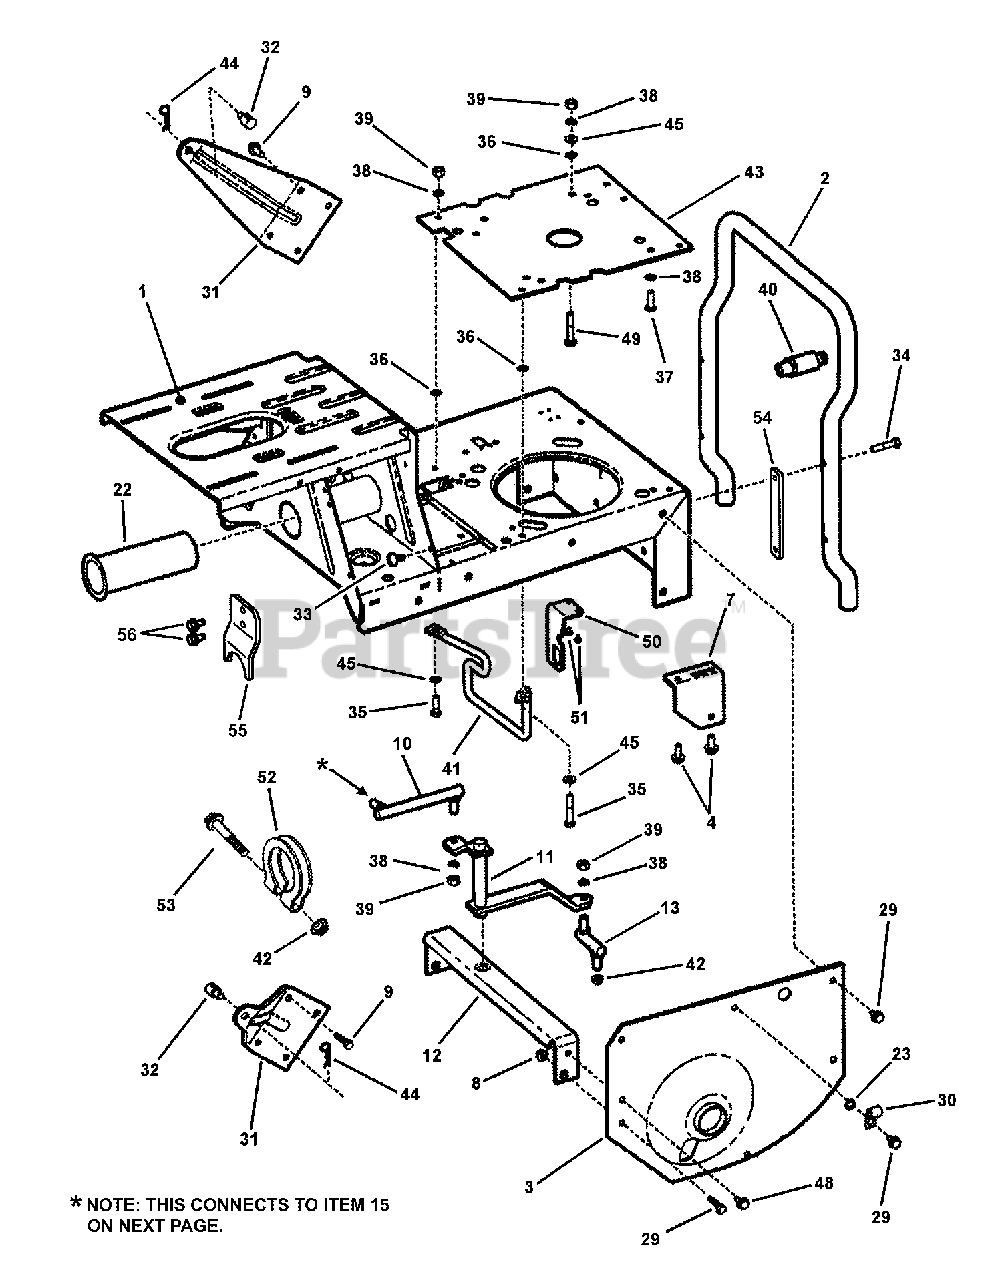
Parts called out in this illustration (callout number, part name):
1	WELDMENT, Main Case (Commercial)
2	BUMPER (1-Piece) (42" Deck)
3	FENDER, Left Hand (Standard)
4	BOLT, 5/16-18 x 3/4" Hex Flange Lock, GR5
7	BRACKET, Drive Support
8	NUT, 5/16-18 Hex Flange Lock, GR5
9	SCREW, 5/16-18 x 3/4" Hex Washer Self-Tap
10	SHIFT LINK, Long
11	WELDMENT, Shift Arm
12	CROSS BRACE
13	SHFT LINK, Short (5/16-24 thread)
22	BUSHING, Pivot
23	WASHER, 5/16" Internal Tooth Lock
29	SCREW, 5/16-18 x 5/8" Hex Washer Self-Tap
30	CLIP, Wire
31	WING, Rear Deck
32	SWIVEL, Adjustable
33	FASTENER, 1/4" Ratchet
34	SCREW, 5/16-18 x 1-1/2" Hex Washer Self-Tap
35	SCREW, 5/16-24 x 1" Hex Head Cap, GR5
36	RETAINER, 5/16" Bolt
37	SCREW, 3/8-16 x 1" Hex Washer Self-Tap
38	WASHER, .32 x .58 x .08 Split Lock
39	NUT, 5/16-24 Hex, GR5
40	ASSEMBLY, Oil Valve
41	BELT GUIDE, 4216
42	NUT, 5/16-24 Flange Lock (Large)
43	PLATE, Engine (Kohler Engine)
44	HAIR PIN, 3/32 x 1-1/2"
45	WASHER, 5/16" Flat
48	SCREW, 5/16-18 x 3/4" Hex Head Cap, GR5
49	SCREW, 5/16-24 x 1-3/4" Hex Head Cap, GR5
50	BRACKET, Switch
51	SCREW, #10-32 x 1/4" Hex Washer Self-Tap
52	TUBE CLAMP
53	SCREW, 5/16-24 x 2-1/2" Hex Head Cap, GR5
54	PLATE, Bumper Spacer
55	BRACKET, Belt Adjuster
56	SCREW, 3/8-16 x 5/8" Hex Washer Self-Tap
